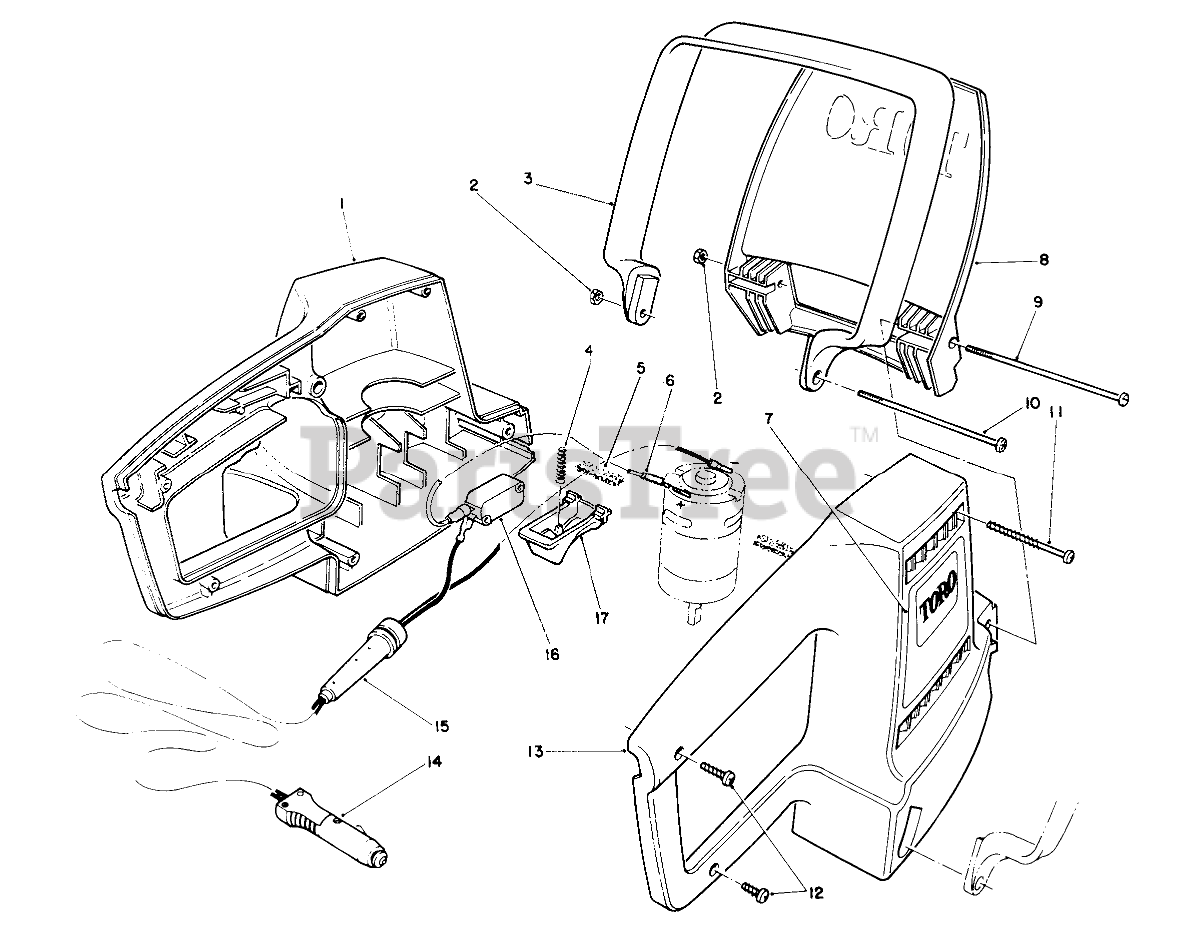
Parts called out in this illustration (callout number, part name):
1	Housing-Handle, L.H.
2	NUT-HJ
3	ASSIST HANDLE
4	SPRING-TRIGGER
5	WIPER
6	WIRE ASSEMBLY
7	DECAL-HEDGE, RT
8	SHIELD
9	SCREW-PPH
10	SCREW-PPH
11	SCREW - #8 X 2.0
12	SCREW-PPH
13	Housing-Handle, R.H.
14	CORD-HEDGE
15	Relief-Strain
16	SWITCH
17	TRIGGER
